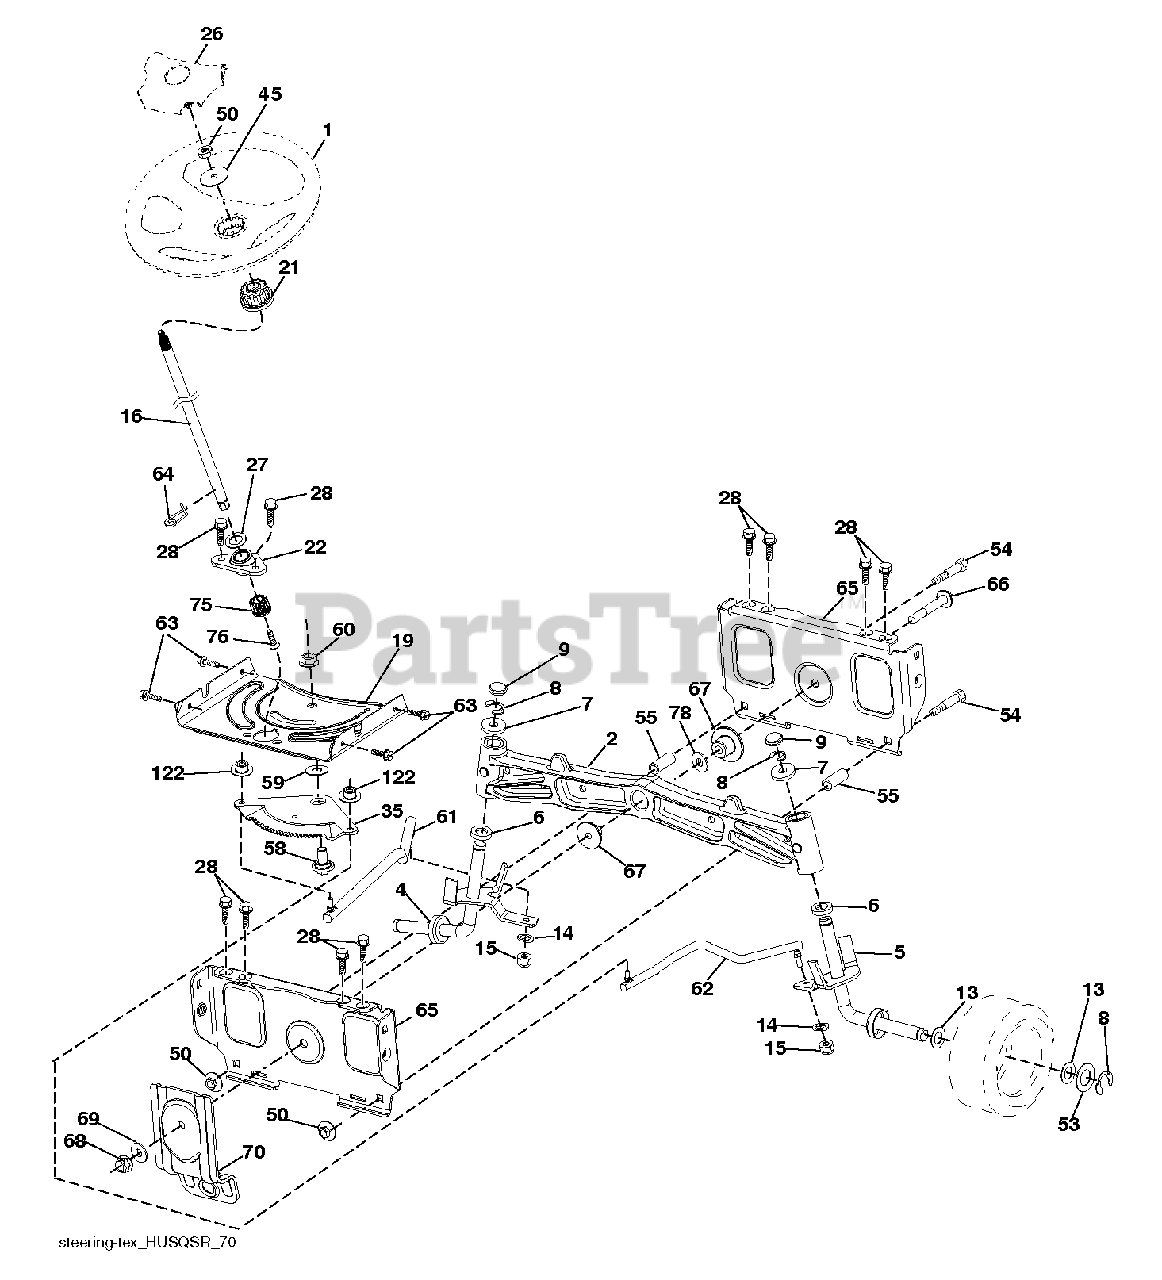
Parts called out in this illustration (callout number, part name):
1	WHEEL.STEER.HUSQ.SR.498.OVMLD
2	AXLE.CAST.IRON
4	SPINDLE.WELDED.LH.16"TEX
5	SPINDLE.WELDED.RH.16"TEX
6	THRUST WASHER
9	CAP.SPINDLE.BLACK
14	SLW 3/8 STD
15	NUT CROWNLOCK 3/8-24
16	SHAFT.STEER.2HIGH.SPLND.PLATED
19	PLATE.STEER.DDL.NLT/NG
21	ADAPTER.WHEEL.STEER.SPLND.ALUM
22	BEARING.SUBASM.SHAFT.STEER.LOW
26	INSERT.CAP.WHL.STRG.HUSQ.PREM
27	WASHER LT
28	SCREW, 3/8-16X3/4
35	GEAR.SECTOR.PLATE.DDL.
45	WASHER.3/8ID.2-3/8OD.12GA.PLTD
50	NUT LOCK FLG 3/8-16 UNC
53	WASHER.HARDENED
55	SPACER.BRACE.AXLE
58	BOLT.SHOULDER.SECTOR.P
59	WASHER.THURST.SECTOR.S
60	NUT FLANGE LOCK 5/8-11
61	LINK.ASM.DRAG.ADJUST.LH.PLATED
62	LINK.ASM.DRAG.ADJUST.RH.PLATED
63	SCREW
64	RETAINER.CLIP.SPRING.S
65	BRACE.AXLE.FRONT.NLT/N
66	BOLT HEX FGHD 7/16-14 X 3 SERR
67	BUSHING.PM.FRONT AXLE
68	NUT.LOCK.FLANGE.7/16
69	WASHER.1.5X.505X.118
70	BRACKET.FRT.DECK.SUSP.RR.MT431
75	PINION.ZINC PLATED
76	SCREW HEAD SOCKET LRVB
78	THRUST WASHER
122	CAP.GEAR.SECTOR.TEX
